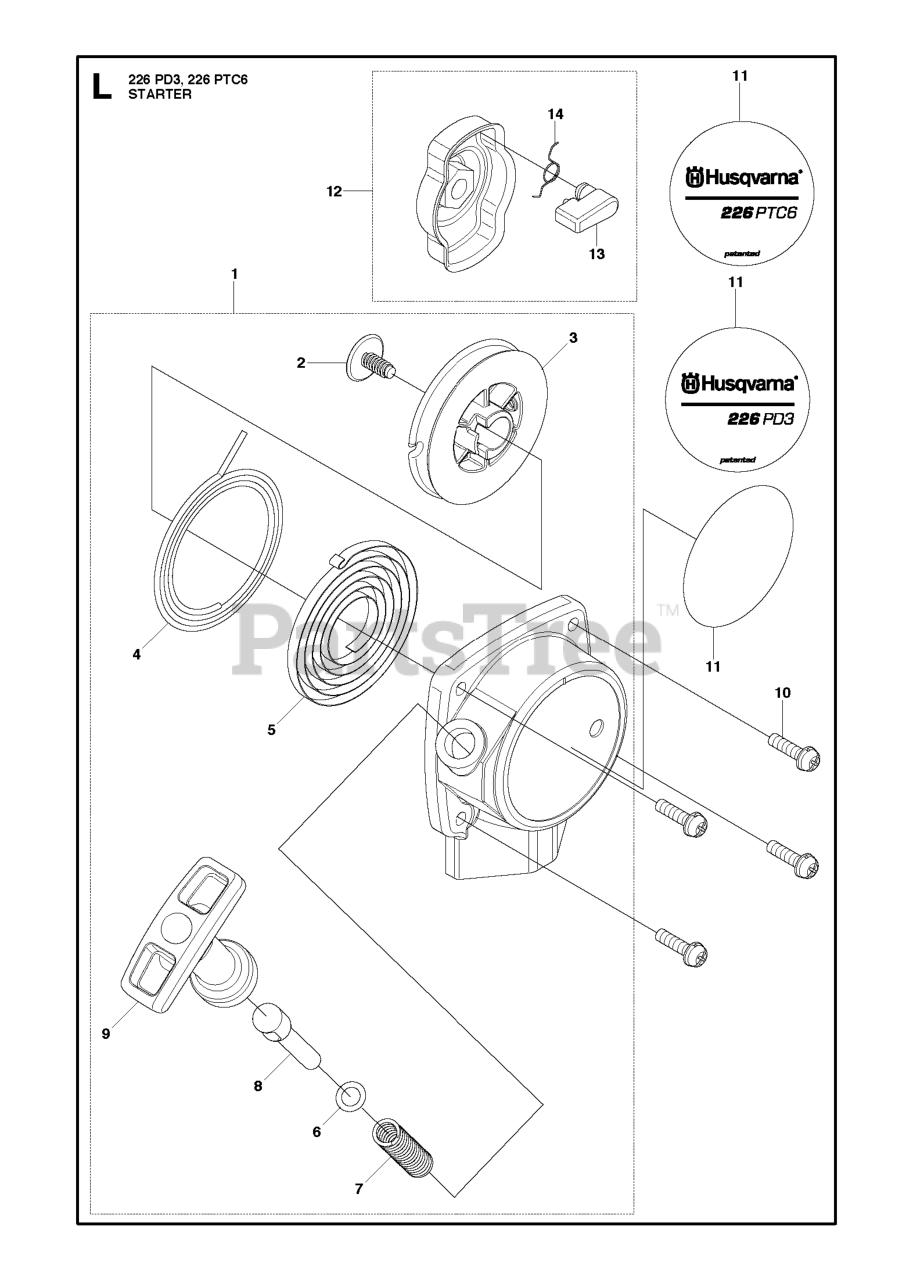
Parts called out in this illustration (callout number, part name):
2	SCREW
5	SPRING, SPIRAL
8	COLLAR (RPLS T160075320)
